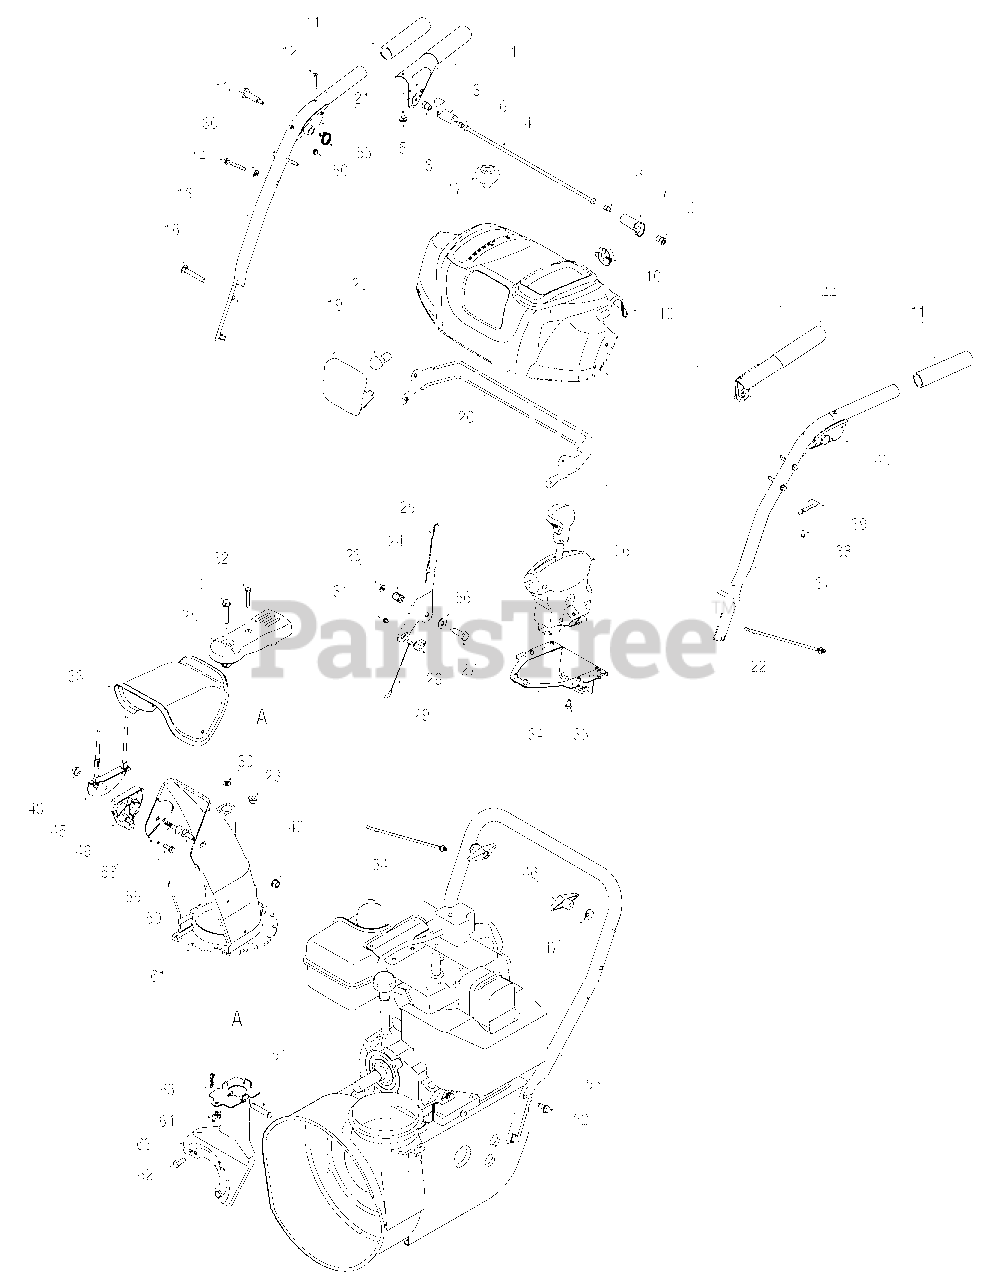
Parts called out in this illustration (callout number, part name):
1	Handle Engagement Assembly
2	Flange Shoulder Screw
3	Lock Plate
4	Pivot Rod
5	Rubber Bumper
6	Screw, 1/4-20 x.375
7	Clutch Lock Cam
8	Shoulder Nut, 1/4-20
10	Light Socket
12	Screw, #10-24 x 0.375
13	Shoulder Screw, 1/4-20 x 1.345
14	Screw, 1/4-20 x 1.750
16	Carriage Screw, 5/16-18 x 2.25
18	Handle Panel, K/L-Style, Black
20	Lamp
21	Handle Clutch Lock - RH
23	Flange Lock Nut, 1/4-20
24	Compression Spring
28	Cable Barrel Holder
29	Speed Selector Cable
30	Flat Washer, .25 x .630 x .0515
31	Screw, #10-16 x .500
32	Hex Screw, 1/4-20 x 1.50
33	Upper Chute
35	Hi-Lo Screw, 1/4-15 x 0.5
36	4-Way Chute Control™ Assembly (Includes Ref.# 57)
38	Screw, #8-16 x 0.50
39	Clutch Lock Spring
40	Steering Control
43	Handle Clutch Lock - LH
44	Handle Engagement Assembly
46	Handle Knob Assembly
47	Saddle Washer
48	Flange Lock Nut, 5/16-18
49	Chute Tilt Cable Guide
50	Hex Lock Nut, #10-24
52	AB Screw, 5/16-18 x 0.75
55	Torsion Spring
58	Carriage Bolt, 5/16-18 x 1.50
59	Hi-Lo Screw, 1/4-15 x .75
60	Carriage Bolt, 5/16-18 x 1.0
61	Lower Chute
62	Hex Screw, 5/16-24 x .750
65	Bow Tie Cotter Pin
